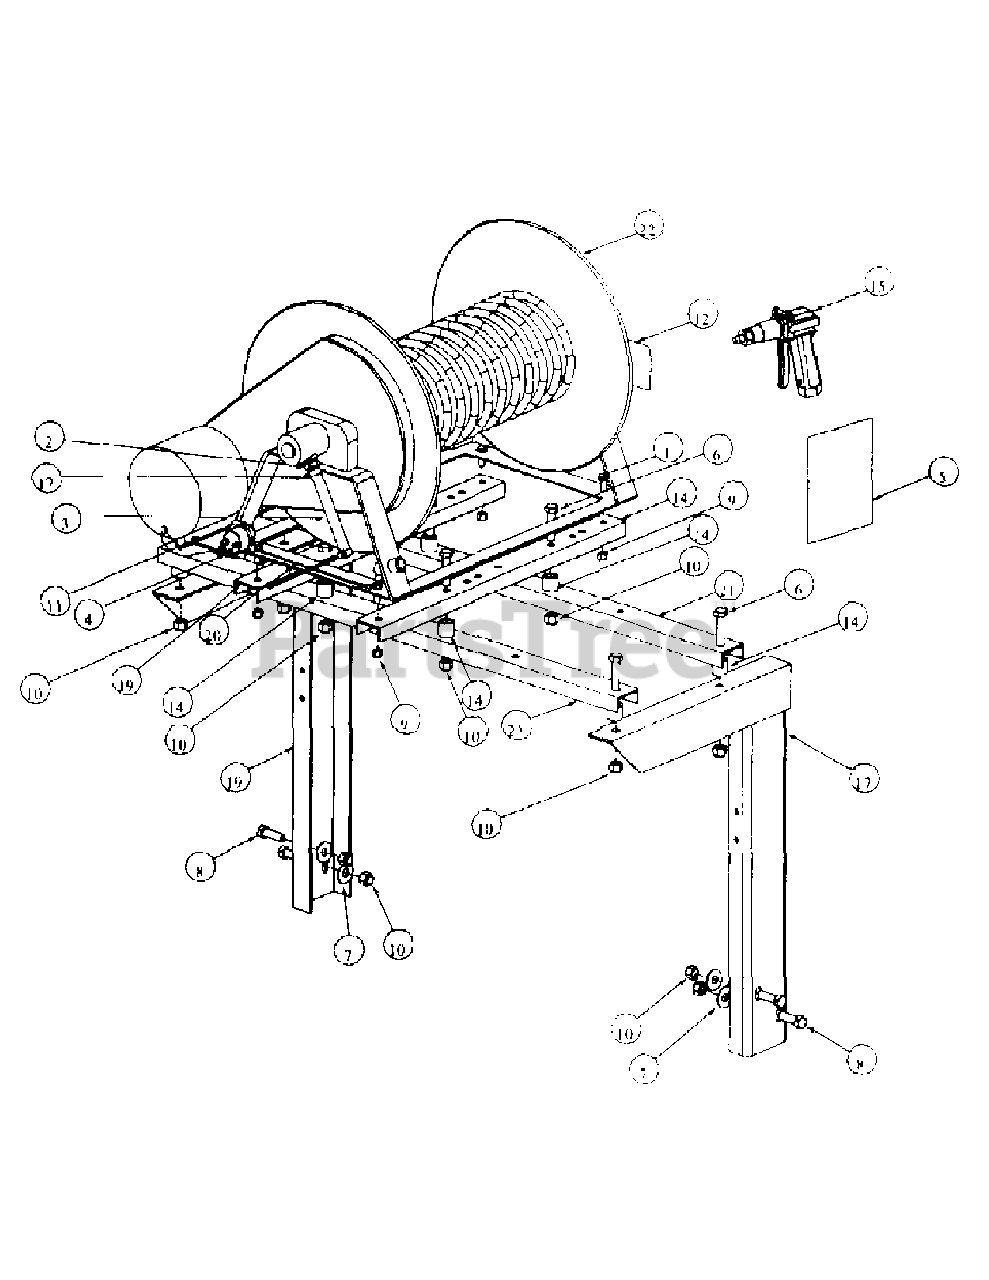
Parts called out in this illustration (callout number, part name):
1	HHCS, 3/8-16 x 1"
2	Hose Barb, 1/2NPT, 1/2
3	Hose, 112" by ft. (sold by the foot)
4	Terminal Ring, 3/8 x #8 Ga
5	Wiring Kit, Elec. Hose Reel
6	HHCS, 112-13, 2.00
7	Flat Washer, 1/2 USS
8	HHCS, 1/2-13, 1-1/2
9	Nut, Lock Nylon Insert, 3/8-16
10	Nut, Lock Nylon lnsert, 1/2-13
11	Cable, Tie, 3/16 x .05 x 7-1/2
12	Decal, Max Hose Length
13	Hose Assembly, 1/2 x 300
14	Spacer Crossbar
15	Spray Gun
16	Hose Clamp, 1/2, 7/8
17	Bracket Assembly, RH Hose Reel
18	Bracket Assembly, LH Hose Reel
19	Channel, Pick-Up Mount Reel Support
20	Wiring Harness
21	Crossmember Hose Reel
